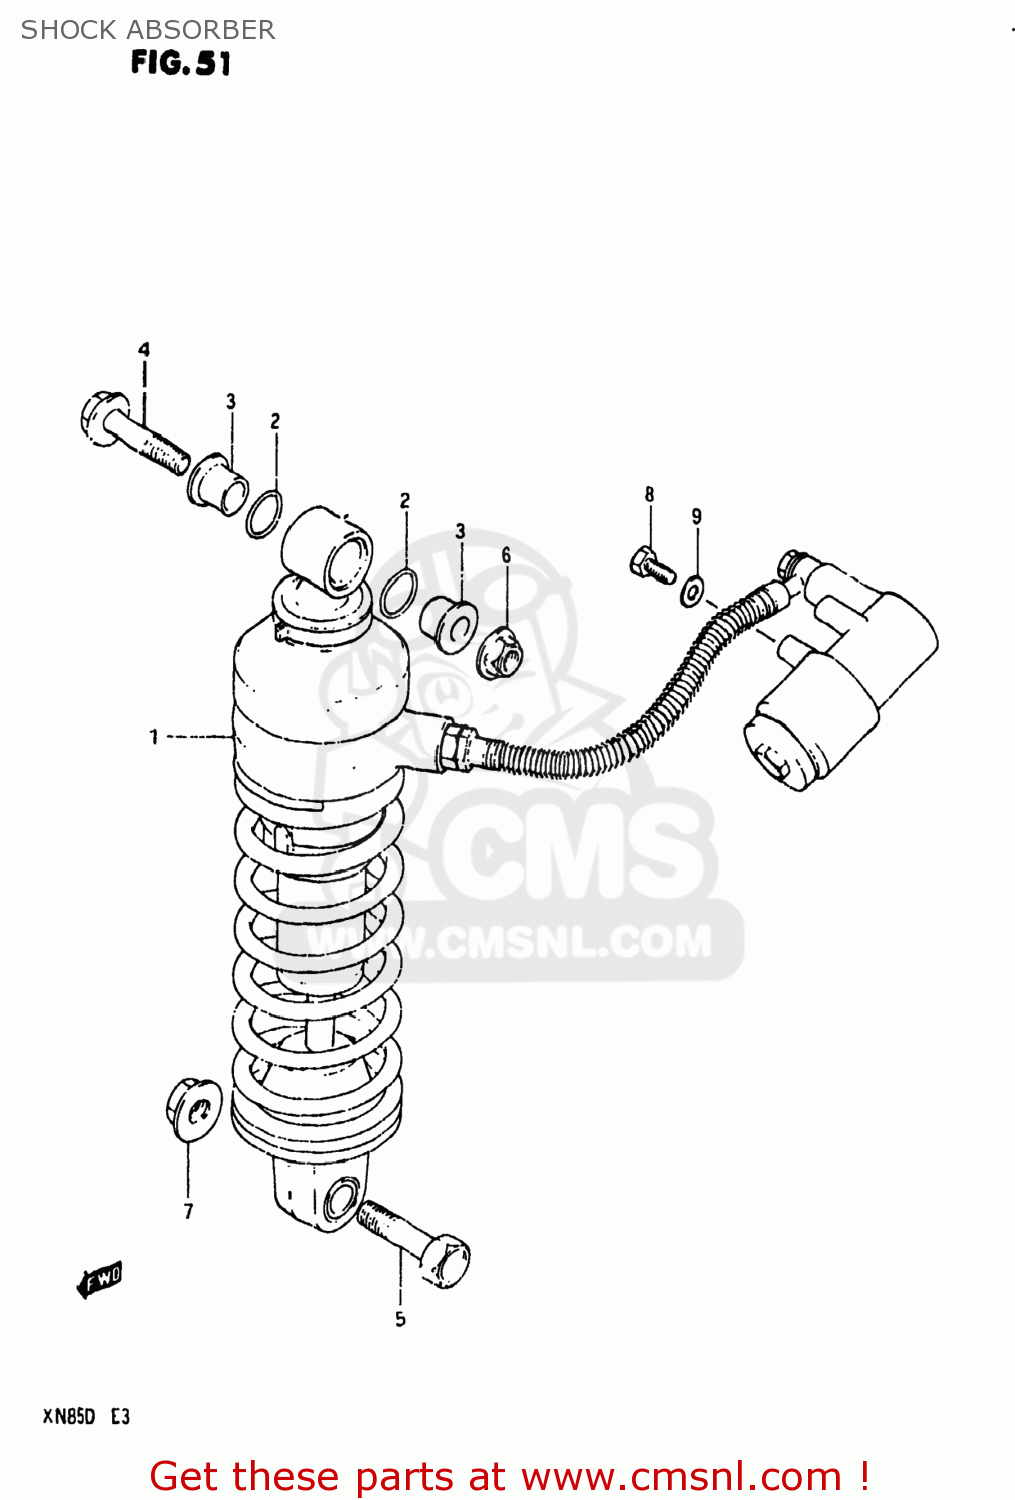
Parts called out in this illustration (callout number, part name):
1	ABSORBER ASSEMBLY,REAR SHOCK
2	DUST SEAL,LEVER CUSHION UNIT
3	SPACER,LEVER CUSHION UNIT
4	BOLT(10X50)
5	BOLT
6	NUT
7	NUT 12MM
8	SCREW(6X12)
9	WASHER
